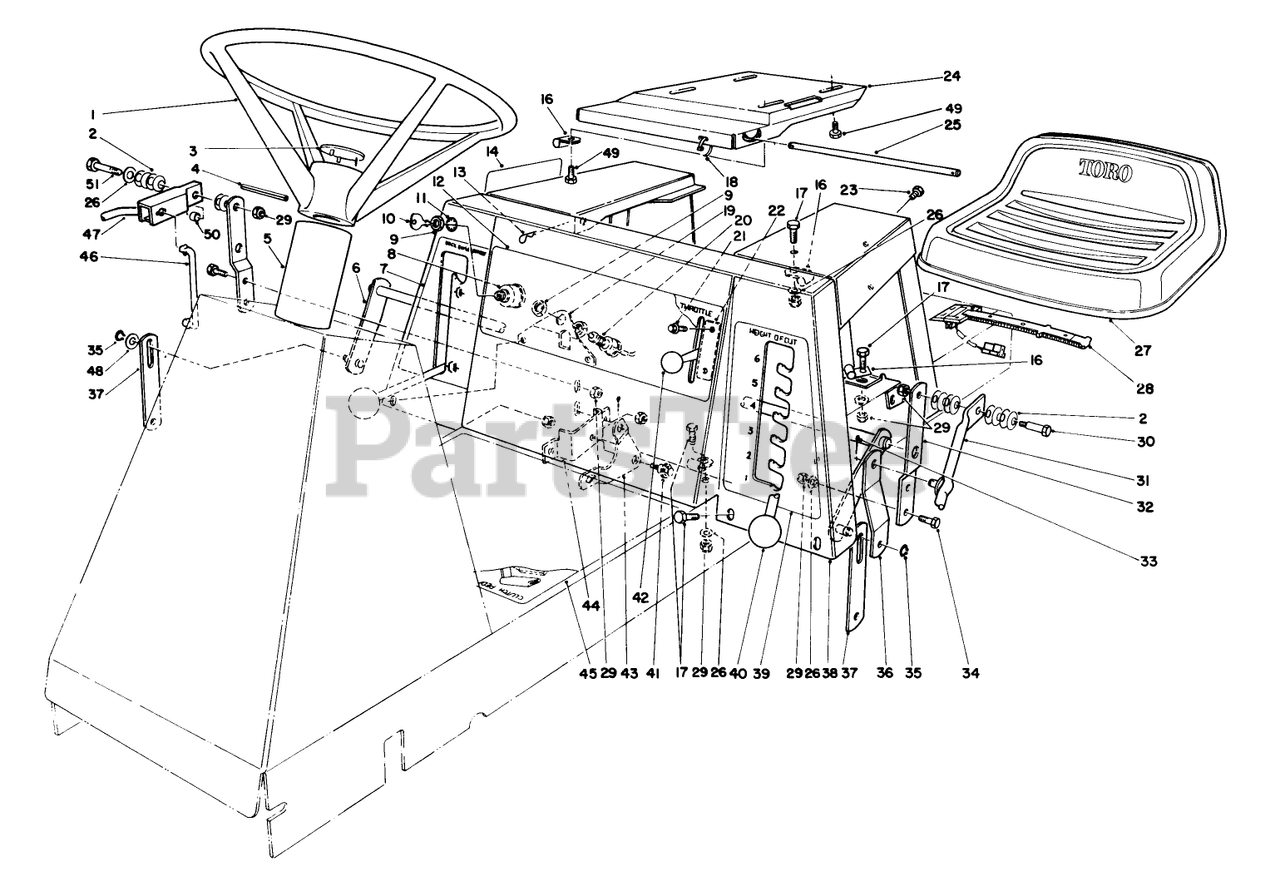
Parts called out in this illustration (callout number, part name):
1	STEERING WHEEL ASM
2	WASHER-BELLEVILLE
4	PIN-ROLL
5	STRG. SHAFT COVER
8	SWITCH-STARTER
9	NUT-HH
11	WASHER-LOCK
16	CLAMP
17	SCREW-HH
18	TIE-CABLE
19	SWITCH MT BRKT
20	DECK SWITCH
21	SCREW-HWHTF
22	THROTTLE CONTROL
23	SCREW-HH
25	SEAT BASE ROD
26	WASHER-PLAIN
28	SWITCH-SEAT
29	NUT-LOCK, NI
30	BOLT-SHOULDER
31	HOC LEVER WA *B
33	PIN-COTTER
34	SCREW-HH
35	RING-RETAINING
39	HOC DECAL
41	SCREW-SHOULDER
43	DECK ENGAGE BELLCRANK
46	BELLCRANK LINK(PLTD)
47	SHIFT LEVER WA *B
48	WASHER-FLAT
49	SCREW-HHF
50	SPACER
51	SCREW-HH
